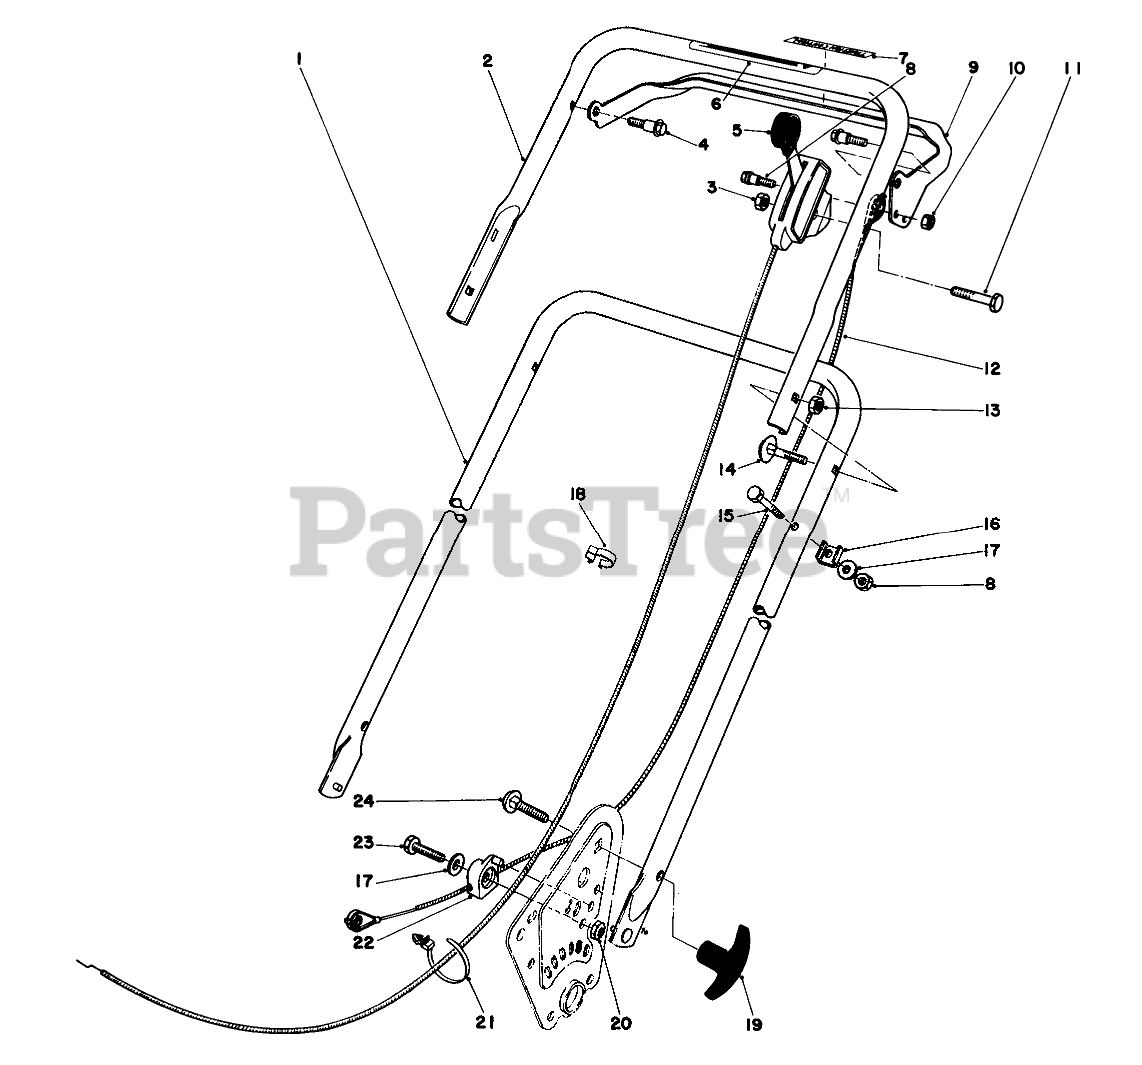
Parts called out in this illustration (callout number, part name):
1	Lower Handle
2	Upper Handle
3	NUT-LOCK
4	Shoulder Bolt
5	Throttle Control
6	Decal
7	Decal-Traction Control
8	BOLT-SHOULDER
9	Squeeze Lever
10	NUT-LOCK, NI
11	SCREW-HH
12	DEMAND HAND CABLE
13	Nut
14	HANDLE SCREW
15	SCREW-HH
16	CLAMP-CABLE
17	WASHER-FLAT
18	BOWDEN CLIP
19	Handle Knob
20	NUT-LOCK, CONE
21	TIE-MOUNT, PUSH
22	CABLE BOSS
23	SCREW-HH
24	Bolt-Carriage
